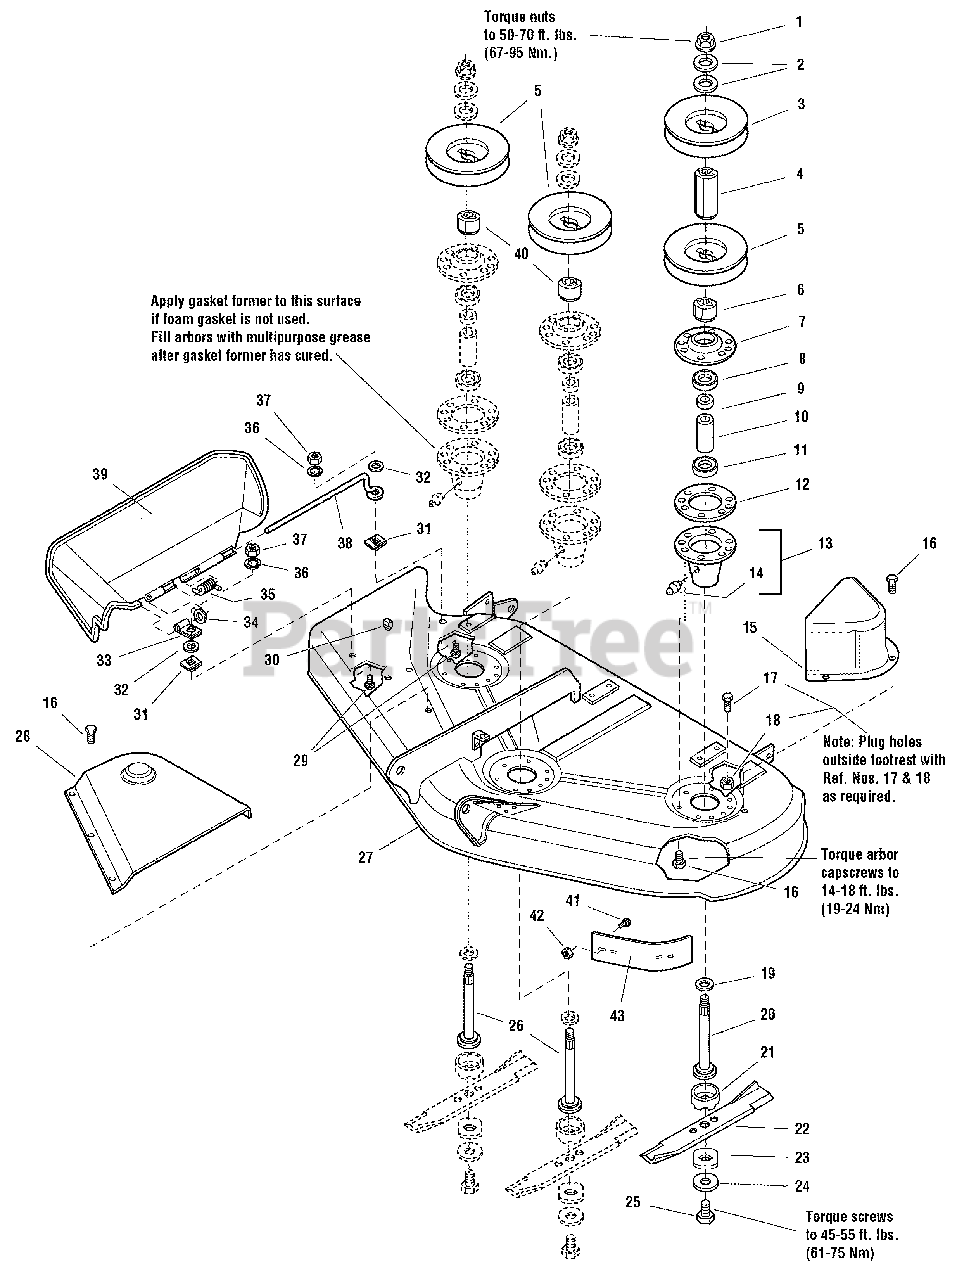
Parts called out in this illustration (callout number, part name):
1	NUT, Hex Flange, 9/16-18
2	WASHER, Bellville, 9/16
3	PULLEY, 4-1/2 O.D.
4	HUB, Double Pulley
5	PULLEY, 4-1/4 O.D.
6	HUB, Double Pulley
7	COVER, Arbor Housing
8	BEARING, Ball, 3/4 x 1-3/4 x 5/8
9	SPACER, 21/32 x 3/4 x 5/8
10	SPACER, 11/16 x 5/32 x 2-11/16
11	BEARING, Ball, 11/16 x 1-9/16 x 15/32
12	GASKET, Foam
13	ARBOR HOUSING ASSEMBLY, (Includes Ref. No. 14)
14	FITTING, Grease
15	COVER, Arbor
16	CAPSCREW, Hex Head Taptite, 5/16-18 x 3/4
17	CAPSCREW, Hex Washer Head, 5/16-18 x 1/2, Black
18	NUT, Hex Flange, 5/16,
19	WASHER, Bellevilled, 9/16, Black
20	SHAFT, Arbor (LH)
21	SHIELD, Grass, Lower
22	BLADE, Mower, 16-1/8 (for 44" Decks)
23	WASHER, Hex, 11/16 x 2
24	WASHER, Spring 15/32, Black
25	CAPSCREW, Hex Head, 7/16-14 x 1
26	SHAFT, Arbor (Center & RH)
27	MOWER HOUSING ASSEMBLY, 44" Mower (Orange)
27	MOWER HOUSING ASSEMBLY, 44" Mower (Red)
28	COVER, Arbor
29	CARRIAGE BOLT, 1/4-20 x 7/8
30	PLUG, Hole
31	NUT, Push
32	WASHER, 1/4, Black
33	CLAMP
34	WASHER, 5/16, Black
35	SPRING
36	WASHER, Lock, 1/4
37	NUT, Hex, 1/4-20
38	ROD, Deflector, Front
39	DEFLECTOR, Plastic
40	HUB, Pulley, Center & RH
41	CARRIAGE BOLT, 5/16-18 x 3/4
42	NUT, Hex Flagne Whiz Lock, 5/16-18
43	BAFFLE, Blowout, 44" & 50"
